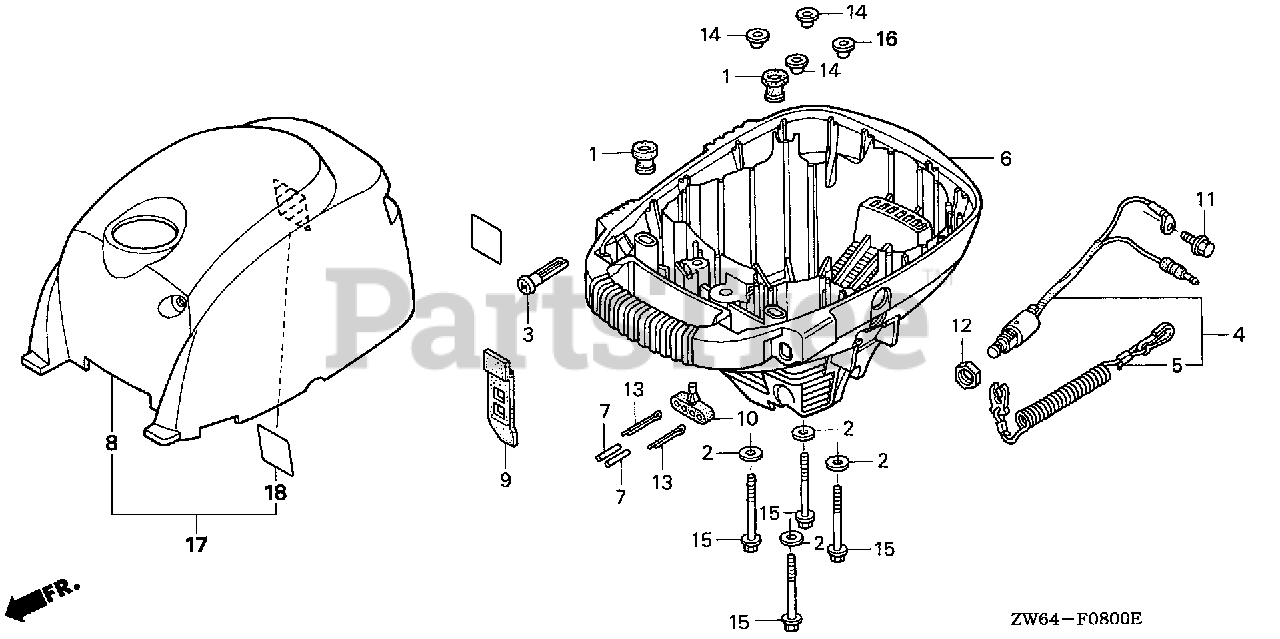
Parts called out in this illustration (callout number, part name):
1	RUBBER, TANK MOUNTING (C)
2	WASHER, PIVOT
3	KNOB, CHOKE
4	SWITCH ASSY., EMERGENCY STOP
5	WIRE, EMERGENCY
6	CASE, ENGINE (LOWER)
7	PIN, SHEAR
8	COVER, ENGINE *NH282MU* (OYSTER SILVER METALLIC-U)
9	BELT, ENGINE COVER
10	HOLDER, PARTS
11	BOLT, FLANGE (5X10) (CT200)
12	NUT, HEX. (16MM)
13	PIN, SPLIT (3MM)
13	PIN, SPLIT (3.0)
14	COLLAR (6X4)
15	BOLT, FLANGE (6X60)
16	COLLAR (6X4)
